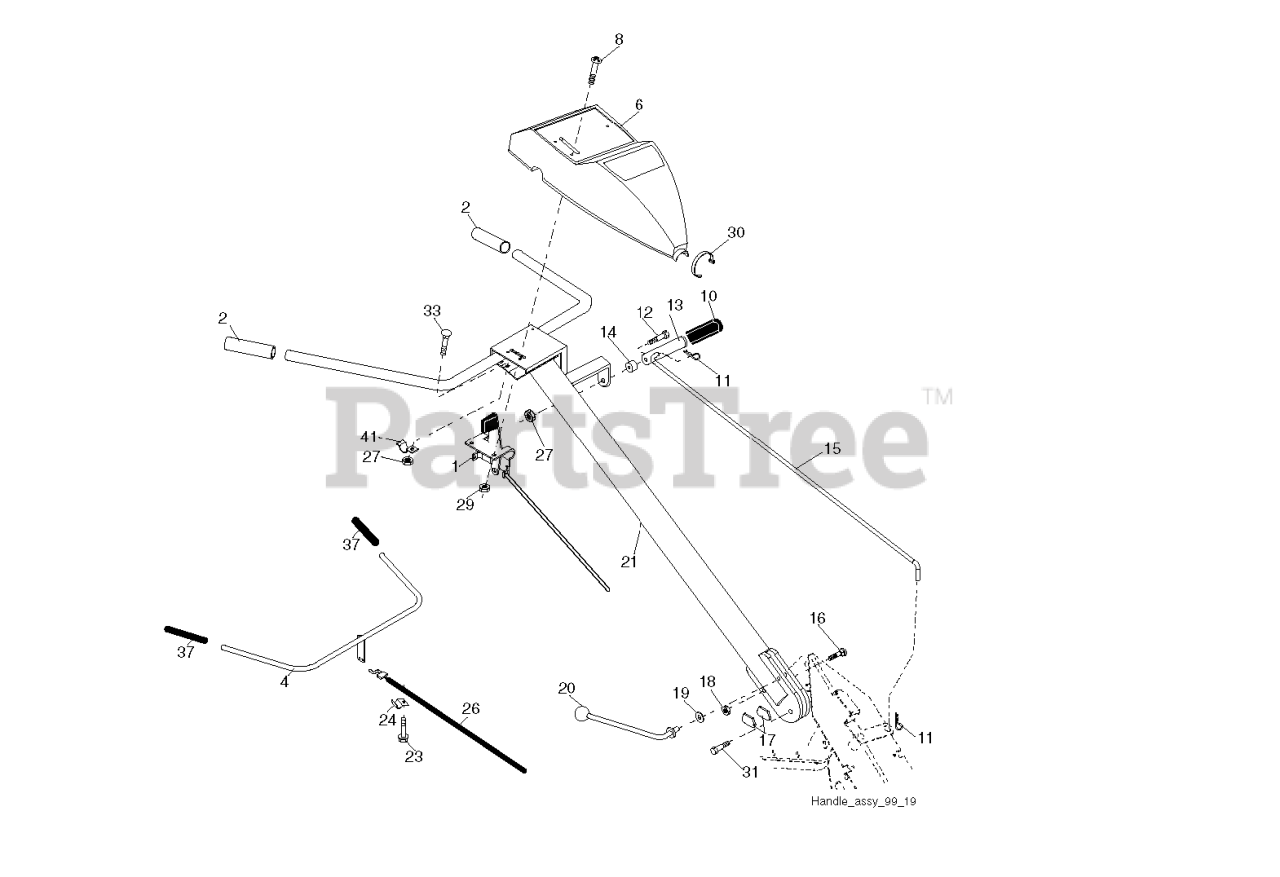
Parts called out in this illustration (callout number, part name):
1	CONTROL.THROTTLE
2	GRIP.1X5.06
4	CONTROL BAR ASSY
6	RP CONTROL PANEL
8	SCREW.PNHD.10-24
10	GRIP T
11	RETAINER M
12	SHOULDER BOLT ST
13	HANDLE.SHIFT.TILLER
14	GROMMET.RUBBER.CRT.TILLER
15	SHIFT ROD CRT
16	BOLT D
17	LOCK.HANDLE.CRT
19	WASHER CRT
20	LEVER.LOCK.CRT
21	REPL BY 532 1805-17
23	TAPPING SCREW
24	CONDUIT.CLIP.PLATED
26	CABLE.CLUTCH
27	NUT T
29	NUT **
30	TIE CABLE CRT
31	BOLT.PIVOT
37	GRIP BAR CRT(1)
41	CLAMP.BAR.CRT.BLACK
